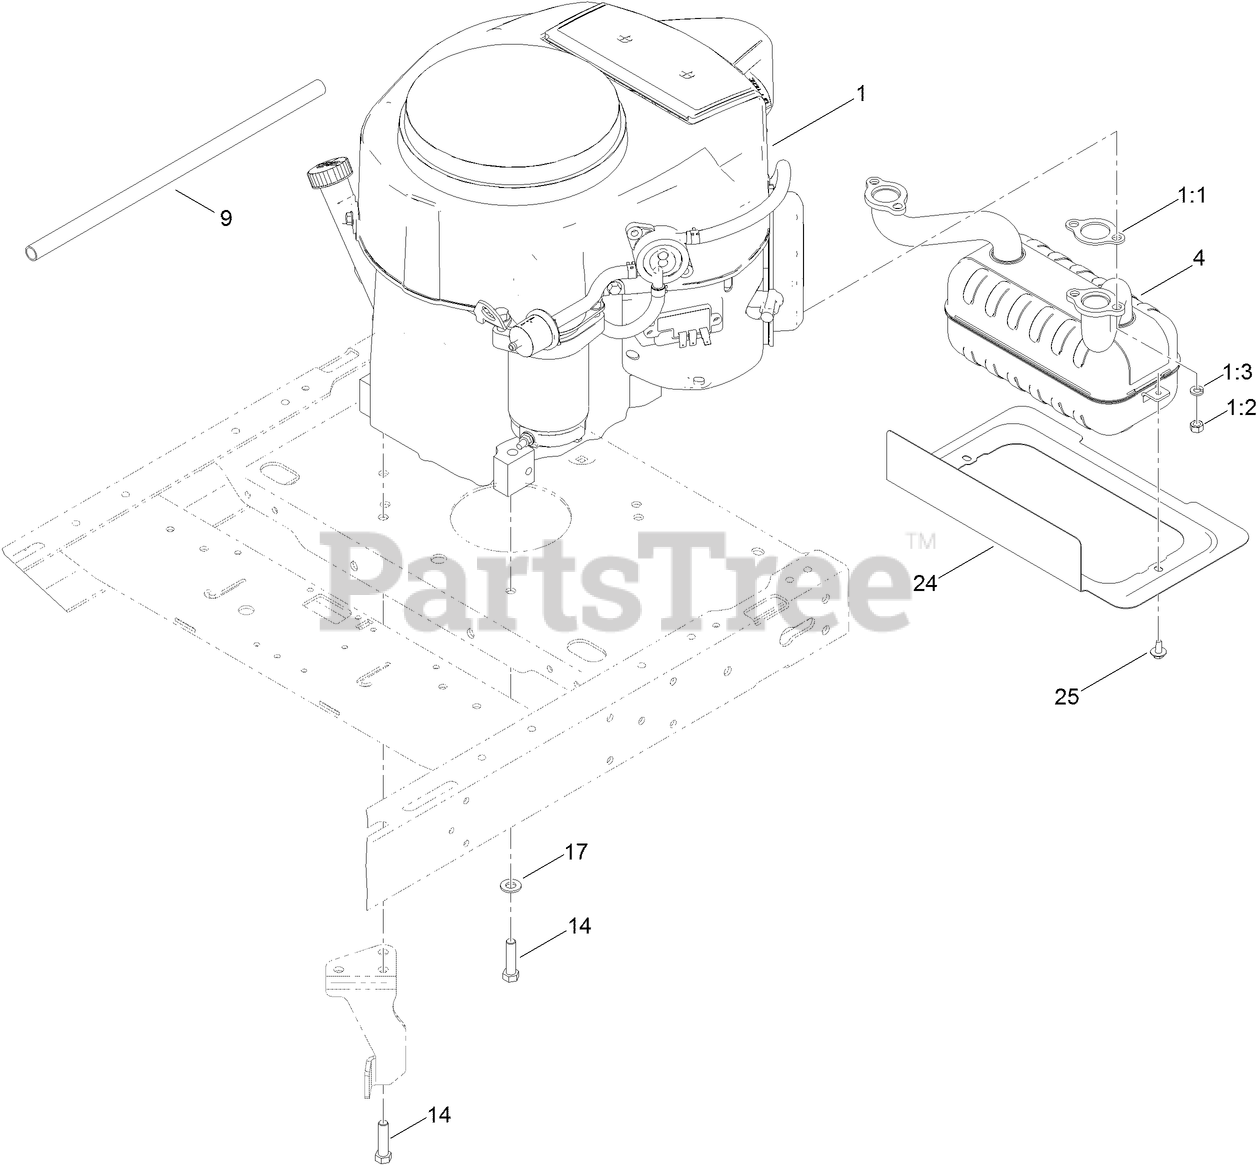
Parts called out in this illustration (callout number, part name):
1:1	GASKET-EXHAUST
1:3	WASHER-LOCK
4	MUFFLER-KAWASAKI
9	TUBE-DRAIN, OIL
14	BOLT-HH
17	WASHER-FLAT
24	SHIELD-HEAT
25	SCREW-HHFTF
